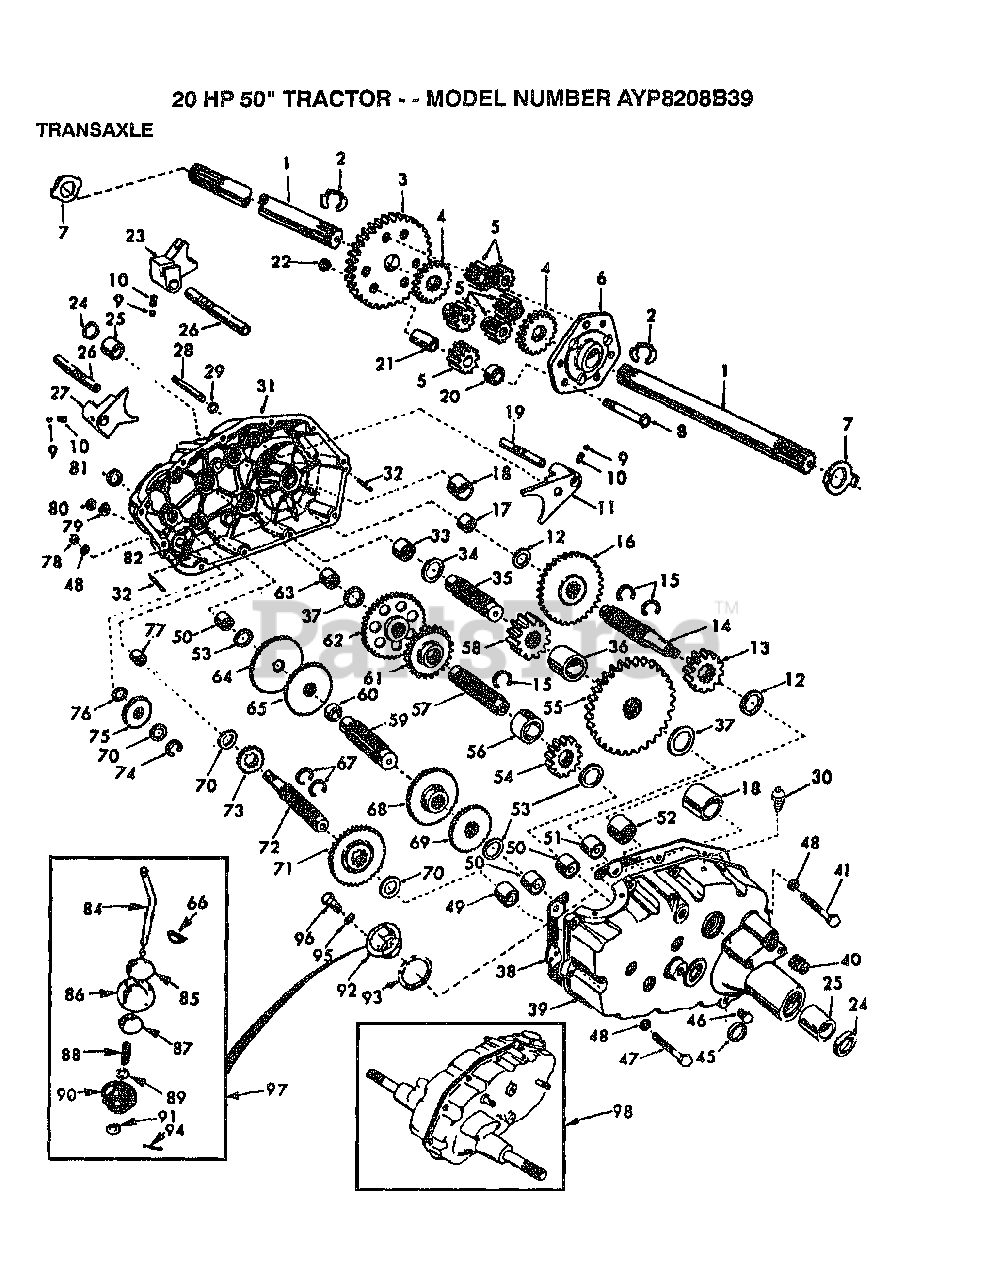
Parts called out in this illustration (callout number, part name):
1	SHAFT.AXLE.T
2	KLIP RING
3	FINAL GEAR T
4	DIFF GEAR T
5	DIFF PINION T
6	DIFF CARRIER T
8	BOLT
11	SHIFT FORK T
12	WASHER .T
13	RED PINION T
14	GEAR SHAFT T
15	SNAP RING T
16	GEAR T
17	"T, BEARING"
18	BEARING
19	SHAFT
20	SPACER T
21	PINION RS
22	GRIPCO NUT
23	FORK T
24	OIL SEAL STD
25	BRNG. T
27	SHIFT FORK T
28	SHIFT SHAFT
29	SEAL T
30	VALVE M
32	PIN T
33	NEEDLE BRNG T
34	RACE T
35	GEAR SHAFT T
37	RACE T
38	GASKET
40	PLUG PIPE
41	BOLT
45	SEAL T
47	HEX BOLT
48	LOCKWASHER
49	"TI, BEARING"
50	NEEDLE BRNG T
51	NEEDLE BRNG T
52	"STD, BEARING"
53	BRNG RACE
54	RED PINION T
55	RED GEAR T
56	PINION SPACER T
57	GEAR SHAFT T
58	FINAL PINION T
59	GEAR SHAFT T
60	SPACER T
61	RED PINION T
62	RED GEAR T
63	RACE T
64	LOW SPEED GEA T
65	REVERSE GEAR T
66	KEY T
67	RING STD
68	INTERMED GEAR T
70	"T, BEARING"
71	CLUSTER GEAR T
72	INPUT SHAFT T
73	LO SPEED PINION T
75	IDLER GEAR T
76	WASHER T
77	BRNG T
78	NUT.HEX.5/16-18
79	WASHER T
80	NUT
81	SEAL STD
84	GEAR SHIFT LVR T
85	CAP T
86	COVER AND PIN T
87	GUIDE BALL T
88	SPRING TI
89	WASHER
90	SEAL T
91	WASHER
92	GEAR SHIFT GA T
93	GASKET T
94	COTTER PIN
95	LOCKWASHER
96	BOLT
97	GEAR SHFT LVR T
98	TRANSAXLE.6SP.GT
